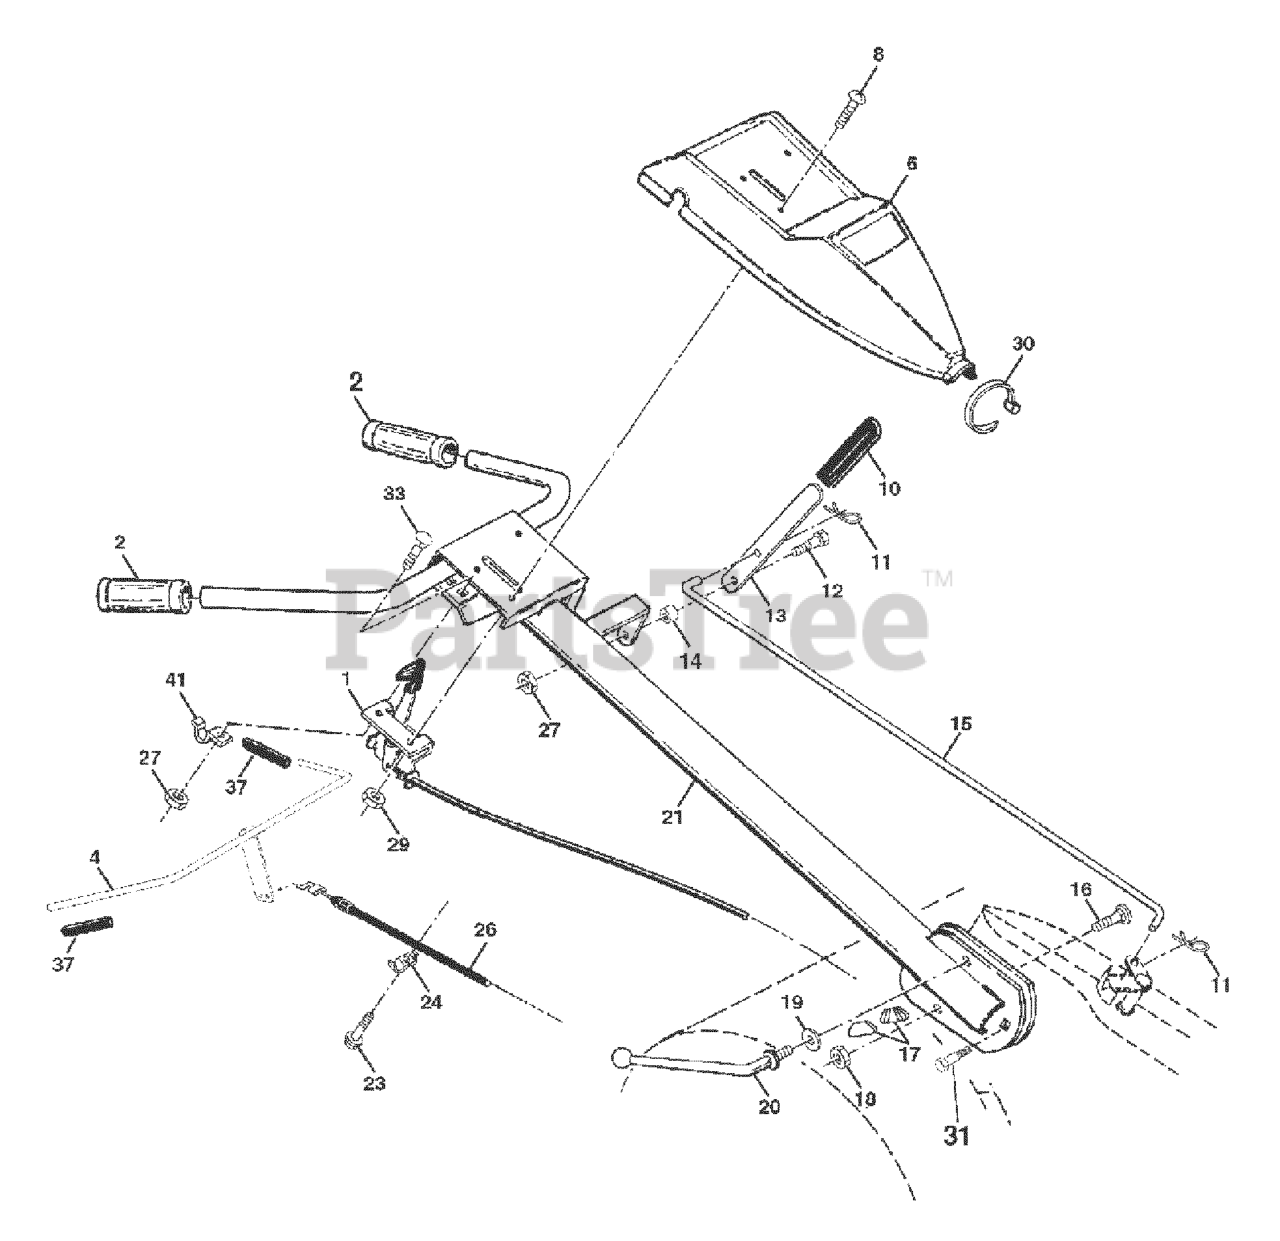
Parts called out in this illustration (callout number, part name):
1	THROTTLE.CONTROL.CRT.TILLER
2	KIT.GRIP.HANDLE.5.00.BLK.VINYL
4	CONTROL BAR ASSY
6	RP CONTROL PANEL
8	SCREW.PNHD.10-24
10	GRIP T
11	RETAINER M
12	SHOULDER BOLT ST
13	SHIFT HANDLE CRT
14	GROMMET.RUBBER.CRT.TILLER
15	SHIFT ROD CRT
16	BOLT D
17	LOCK.HANDLE.CRT
19	WASHER CRT
20	LEVER.LOCK.CRT
21	REPL BY 532 1805-17
23	TAPPING SCREW
24	CONDUIT.CLIP.PLATED
26	CABLE.CLUTCH
27	NUT T
29	NUT **
30	TIE CABLE CRT
31	BOLT.PIVOT
33	BOLT
37	GRIP BAR CRT(1)
41	CLAMP.BAR.CRT.BLACK
